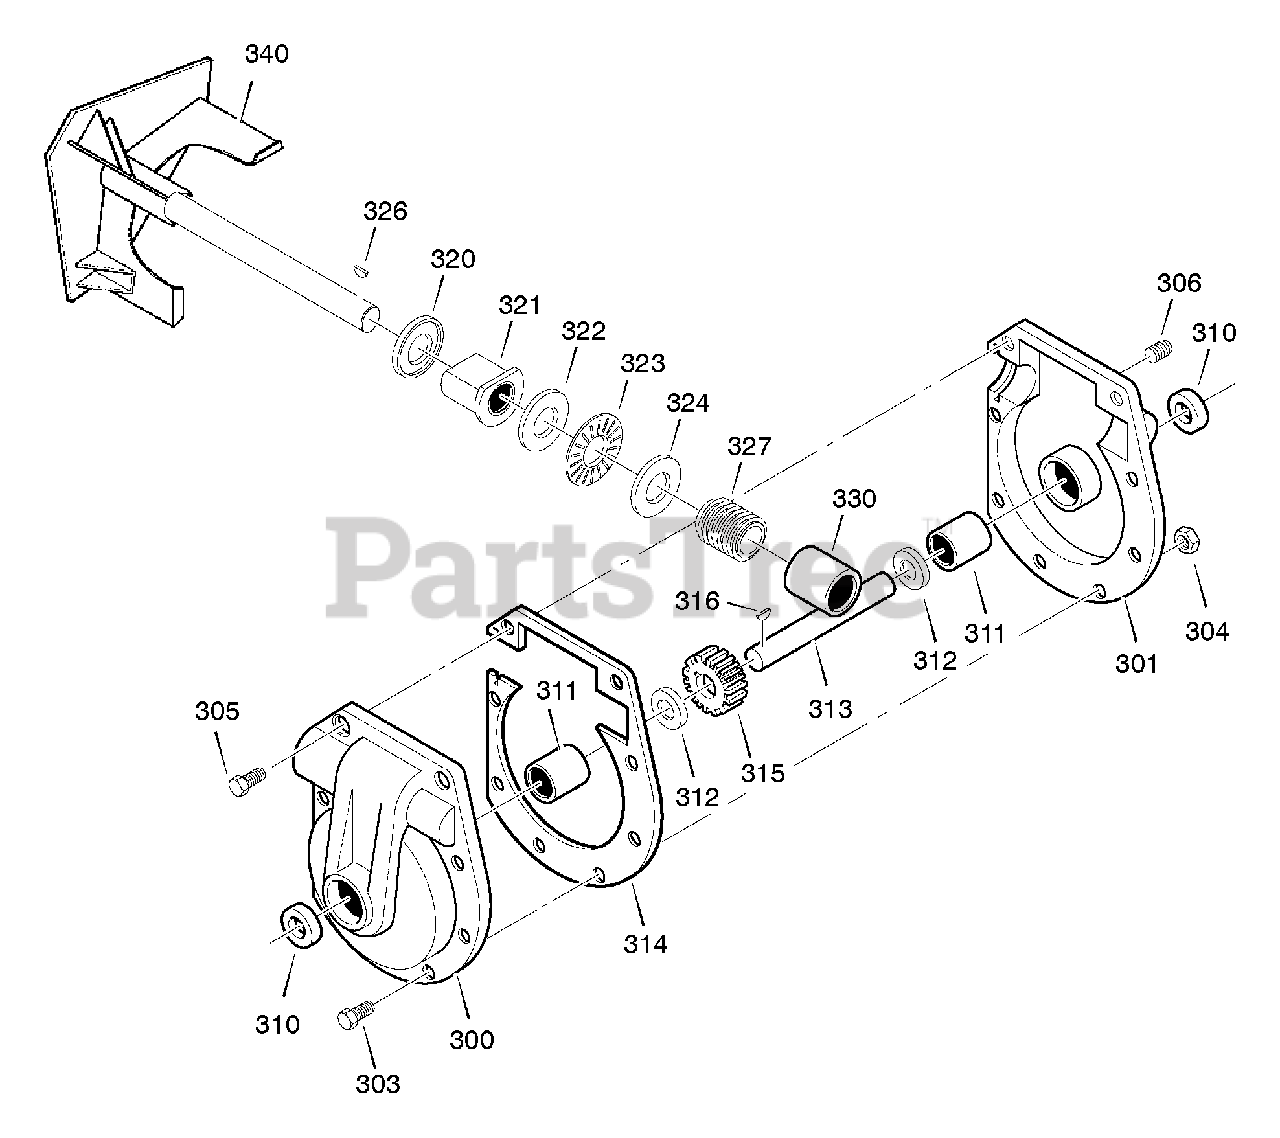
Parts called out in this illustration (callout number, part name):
300	CASE, GEAR, RH
301	CASE, GEAR, LH
303	SCREW, 5/16-24 x 1.00
304	NUT, 5/'16-24
305	SCREW, 5/16-24 x 1.50
306	PLUG, PIPE 0.25-18
310	SEAL, OIL
311	BEARING, SLEEVE
312	WASHER, FLAT
313	SHAFT, AUGER OUTPUT
314	GASKET, GEAR BOX
315	WORM GEAR
316	KEY, WOODRUFF #91
320	RING, QUAD 0.924 ID
321	BEARING, FLANGE
322	WASHER, FLAT
323	BEARING, ROLLER
324	WASHER, FLAT
326	KEY
327	WORM
330	BEARING, SLEEVE
340	IMPELLER
